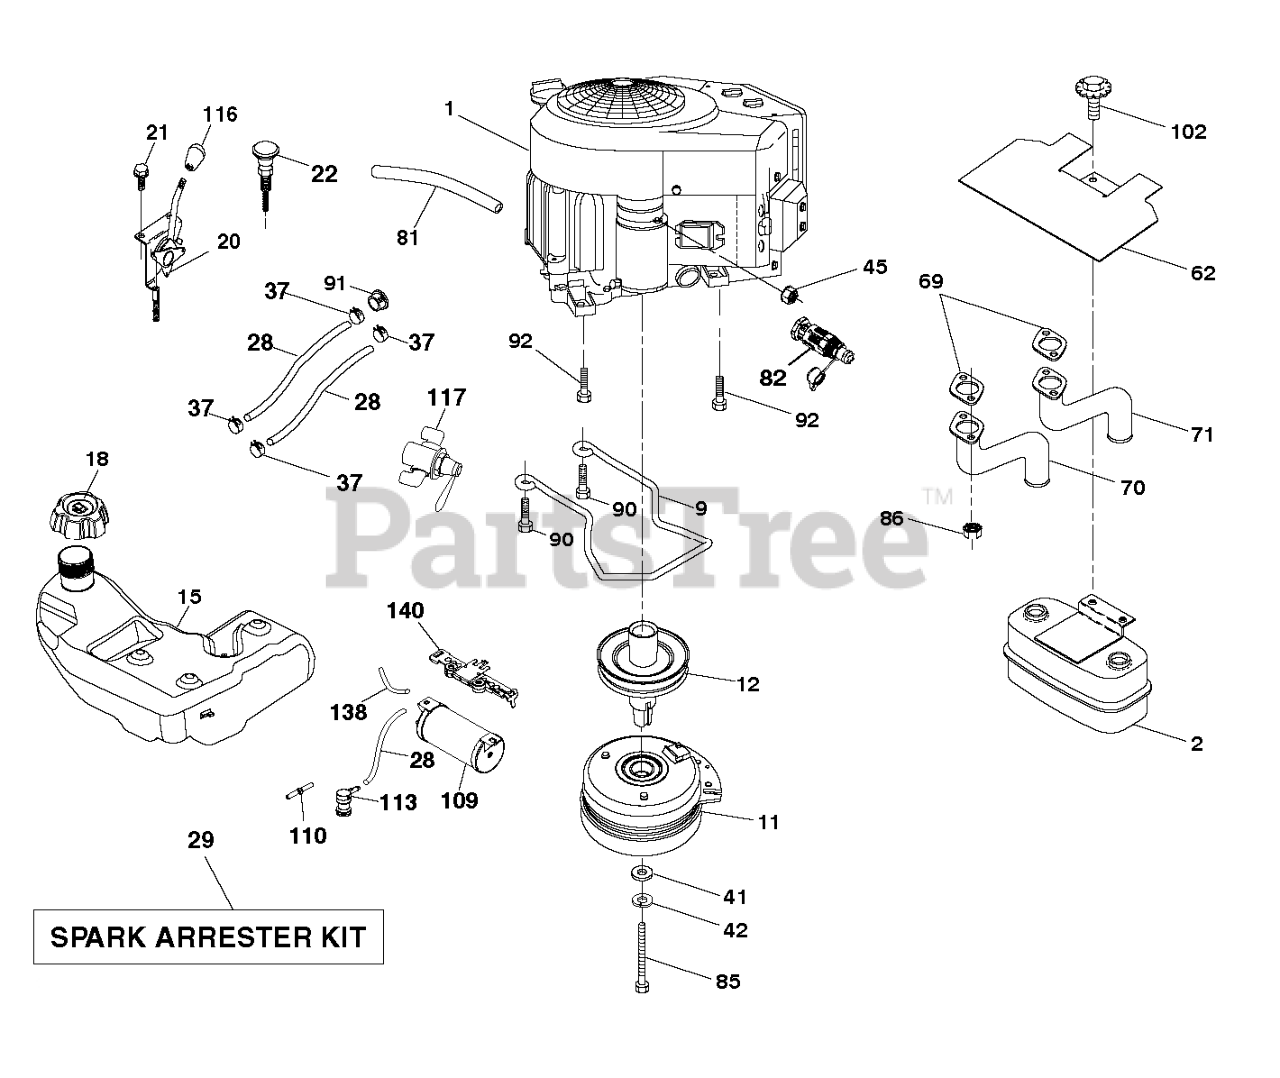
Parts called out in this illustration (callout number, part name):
2	MUFFLER.ASM.TWIN.MNTG.BRACKET
9	KEEPER.BELT.ENG.4.25"2.BLT.431
11	CLUTCH. 5.0 PD. 2.5 OFFSET
12	PULLEY.EXTENDED.SHAFT.GROUND
15	TANK.ASM.FUEL.4R.GAL.EPA.18
18	CAP ASSY FUEL 3" GRAY
18	CAP.ASSY.FUEL.3".N-EPA.BLK.428
18	FUEL CAP
20	CONTROL.THROTTLE.PRO.
20	CONTROL.THROTTLE.PRO.KOHLER
20	THROTTLE.KOHL.PRO.#88PAD_46"
21	SCREW.#10 X 0.750.BOS
22	CONTROL, CHOKE
22	CONTROL.CHOKE.ERGO.PUSH-IN.BLA
28	LINE.FUEL.64"REAR.EMIS
28	HOSE 1/4" LOW PERMEATION FUEL
29	KIT.SPARK ARRESTOR 794945 B&S
37	HOSE CLAMP
42	WASHER 7/16 LOCK
45	NUT
62	SHIELD.HEAT.MUFFLER
69	GASKET.EXHAUST.KOHL.CV18-CV26
69	GASKET
70	PIPE.EXHAUST.LH.CV18/20
70	TUBE.EXHAUST.LH.FR961/FR730
71	TUBE.EXHAUST.RH.FR961/FR730
71	PIPE.EXHAUST.RH.CV18/20
81	TUBE, DRAIN OIL ASM.
82	VALUE.OIL.DRAIN
85	BOLT.HEX.7/16-20X5.GR5.GREEN
86	NUT.HEX.FLANGE.TOPLOCK
90	SCREW 3/8-16X1
91	BUSHING.1.375OD
92	SCREW 3/8-16X1
102	SCREW
109	CANISTER CARB, FLEX TECH, 6.3
110	VALVE.ASM.ANTI-SLOSH
113	VALVE.SLANT.CARTRDG.90 DEG.TEX
116	KNOB - SHIFT
117	VALVE FUEL RESERVE
138	RP PURGE LINE
140	BRACKET BRACKET, CARBON CAN, F
